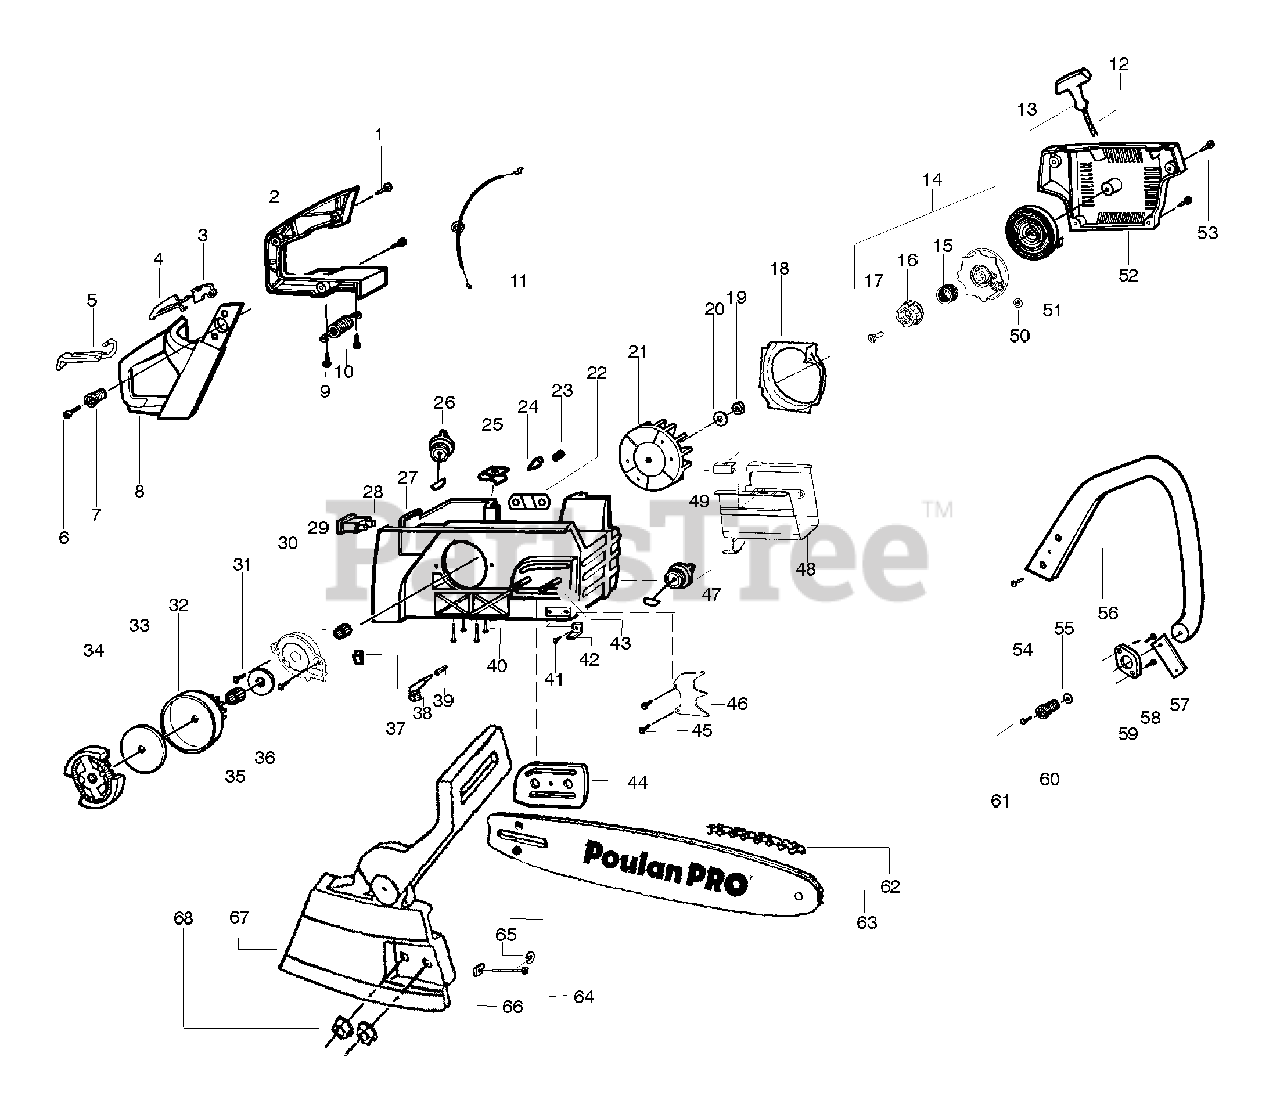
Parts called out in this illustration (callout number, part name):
2	Cover-Handle
3	Trigger-Throttle
4	Lockout-Throttle
5	Lever-Choke
7	Spring-Isolator
8	Handle-Rear
10	Spring-Isolator
11	Assy-Throttle Cable
12	Kit-Rope
13	Handle-Starter
14	Kit-Starter EPS
15	Spring EPS
16	Hub-Starter EPS
17	Screw-Shoulder
18	Plate-Baffle Fan
19	Nut-Flywheel
20	Washer-Flywheel
21	Assy-Flywheel
22	Plate-Support
23	Plug-Vent
24	Valve-Check
25	Nut-Speed
26	Assy-Fuel Cap
27	Assy-Chassis
28	Kit-Switch
29	Worm-Oil Pump
30	Assy.-Oil Pump
32	Kit-Clutch Drum
33	Washer-Clutch
34	Assy-Clutch
35	Bearing-Clutch
36	Washer-Thrust
37	Seal-Oil
38	Pickup-Oil
39	Filter-Oil
42	Chain Catcher
43	Bar Bolt
44	Bar Plate
46	Kit-Spike Assy
47	Assy-Oil Cap
48	Shield-Heat
49	Clip-"U"
51	Spring-Recoil
52	Housing-Fan
55	Washer
56	Handle-Front
57	Front Strap-AV
58	Screw-Plate
59	Plate-Isolator
60	Spring-Isolator
62	Chain"- 20"
63	Bar -20"
64	Kit-Bar Adjust
65	Retainer-Bar Adjust
66	Pin-Bar Adjust
67	Assy-ChainBrake
68	Nut-Bar Mounting
